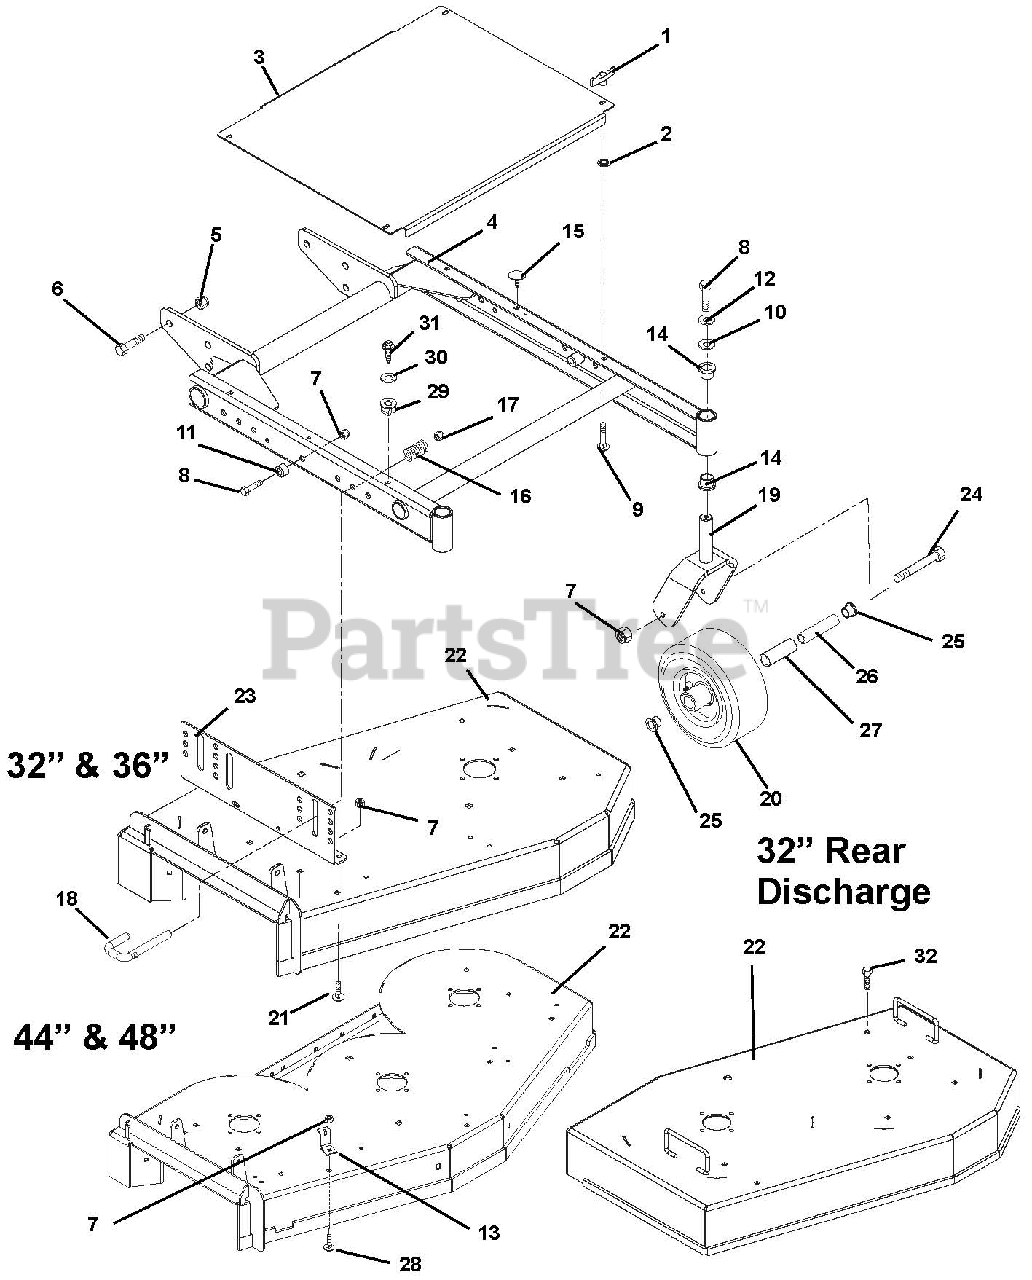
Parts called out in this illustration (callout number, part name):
1	Knob- Wing .312-18
2	Nut-Push .312
3	Cover, Belt Pro Mower
3	Cover- Belt- Pro- 32
3	Cover- Belt- Pro- 44
4	Weldment - Mower Frame 36"
4	Weldment - Mower Frame 48"
4	Weldment - Mower Frame 44"
4	Weldment - Mower Frame 32"
5	Nut-Locking-Nylon .625-11
6	Bolt-Hex .62-11 x 1.50
7	Nut-Locking-Top-Flange .38-16
8	Bolt-Hex .38-16 x 1.25 Grade 5
9	Bolt-Round Head Square Neck .31-18 x 1.00
10	Washer-Flat-Steel .38 x 1.50 x .125
12	Washer-Locking .38 x .094 Regular
13	Anchor, Spring
14	Bushing-Flange 1.00 x 1.25 x 1.50 x 1.50
15	Bumper Grommet .125 x .25 Dia.
16	Spring-Compression .058 x .65 x 2.13
17	Nut-Locking-Center .50-13
18	Pin- Latch
19	Weldment-Caster Fork
20	Wheel 9 x 3.50
21	Bolt-Round Head Square Neck .38-16 x 1.00 Grade 5
22	Kit, 36" Fixed Mower Deck with Decals
22	Kit, 48" Fixed Mower Deck with Decals
22	Kit, 44" Fixed Mower Deck with Decals
22	Kit, 32" Fixed Mower Deck with Decals
22	Kit, 32" Rear Discharge Fixed Mower Deck with Decals
23	Kit-Mower Side Support Bracket-Right Hand and Left Hand
24	Bolt-Hex .38-16 x 5.50
25	Bearing-Retainer
26	Bearing .625 x .380 x 4.08
27	Bearing-Roller
28	Bolt-Round Head Square Neck .38-16 x .75 Grade 5
29	Grommet, Plastic
30	Washer-Flat-Steel .281 x .62 x .065
31	Screw-Tapping .25-20 x .50 Hex Washer Head
32	Bolt-Hex .38-16X1.00 Grade 5
